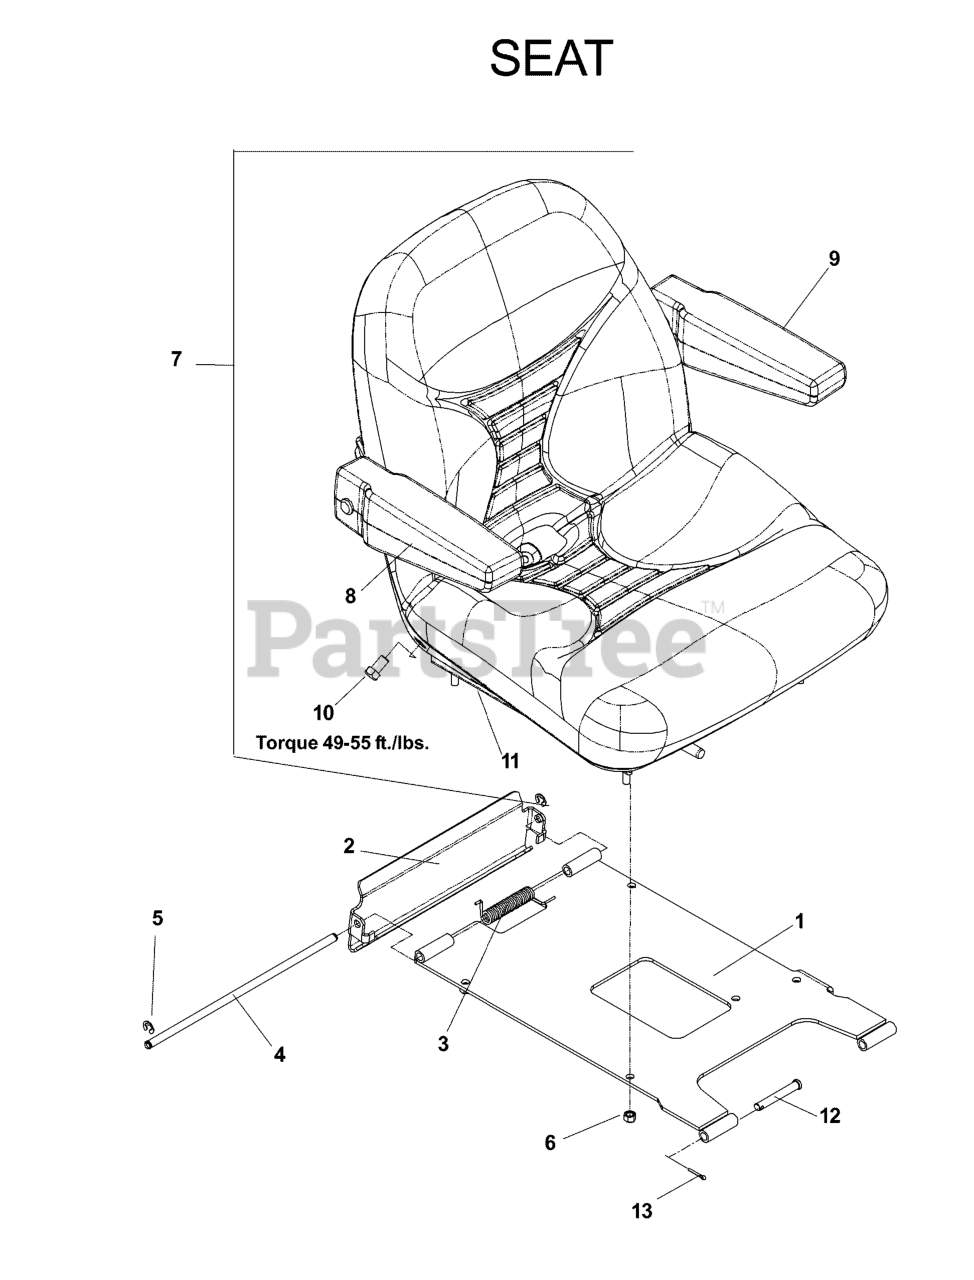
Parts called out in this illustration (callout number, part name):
1	SEAT MOUNTED WLDMT
2	SEAT LATCH BRACKET
3	TORSION SPRING (SEAT)
4	SEAT LATCH ROD
5	E RING 3/8"
6	NUT 5/16 NYLOC
7	SEAT
8	ARMREST KIT, RT SQUARE END
9	ARMREST KIT, LT SQUARE END
10	HCS 7/16-20 X .75 GD 5
11	TRACK ADJUSTMENT KIT
12	CLEVIS PIN 3/8
13	RP_COTTER PIN 1/8 X 3/4
